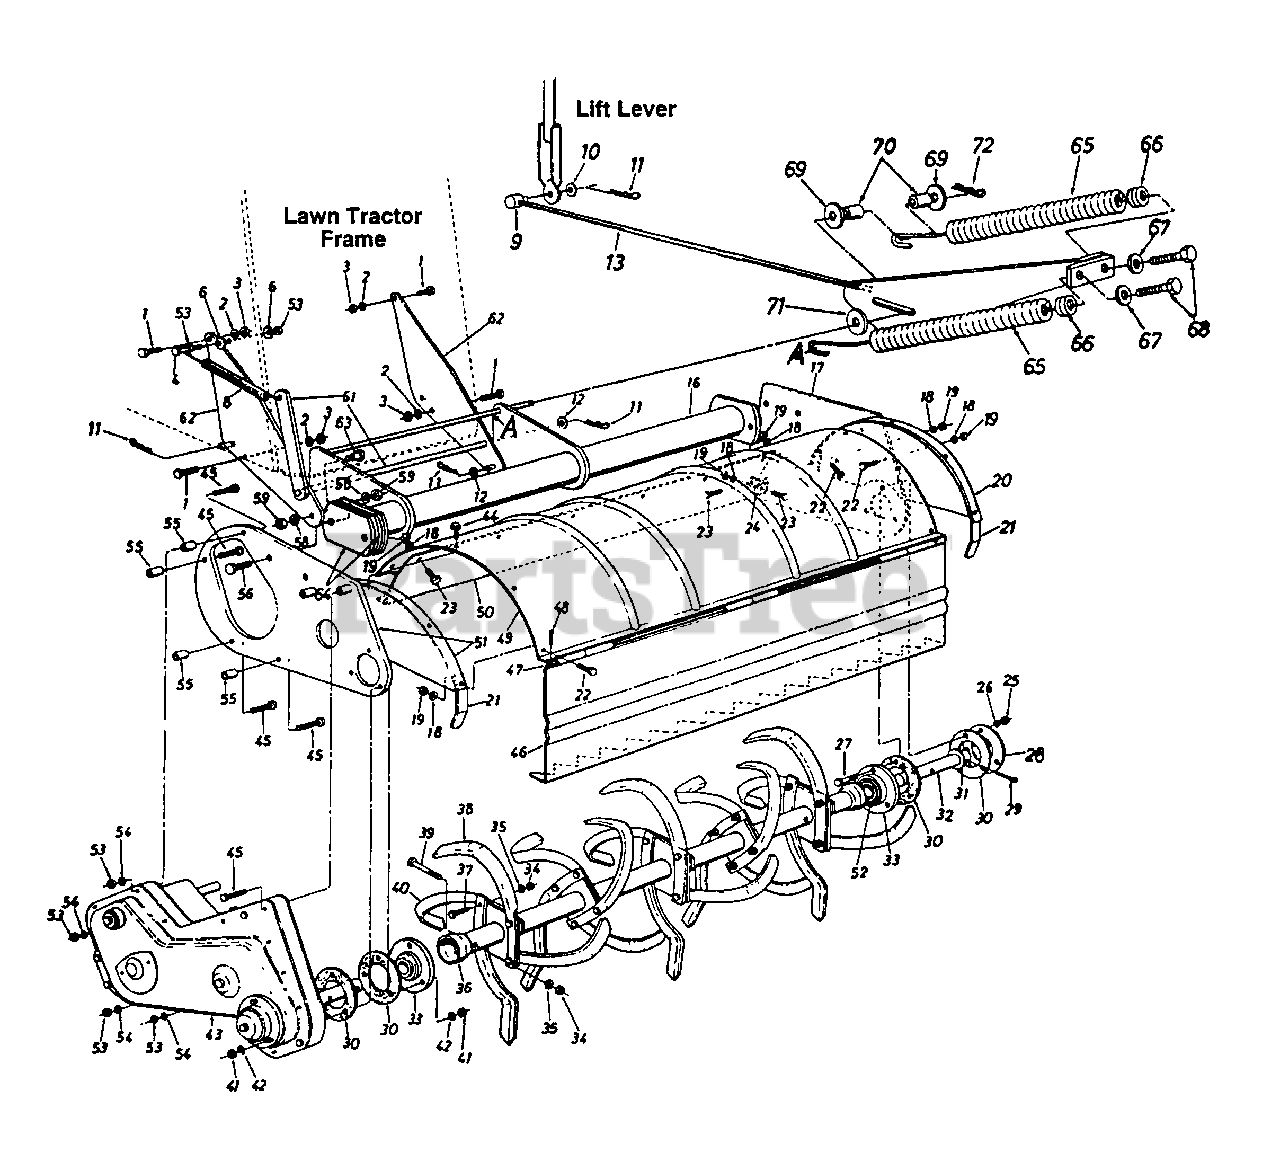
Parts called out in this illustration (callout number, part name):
1	Hex Bolt 3/8-24 x .88" Lg.
2	L-Wash. 3/8" I.D. - H.D.
3	Hex Nut 3/8-24 Thd.
4	Hex Bolt 1/4-20 x 1.25" Lg.
6	Bell-Wash. 1/4" I.D.
8	Ext. Spring 7.75" Lg.
9	Adjustment Ferrule 1/2-13 Thd.
10	Fl-Wash. .64 I.D. x 1.24" O.D. x .06"
11	Intem. Cotter Pin 1/2" Dia.
12	Fl-Wash. .51" I.D. x 1.0" O.D. x .06"
16	Pivot Bracket Assembly
19	Hex Nut 5/16-24 Thd.
23	Hex Bolt 5/16-24 x .62" Eg.
24	Chute Pivot Bracket
25	Hex L-Nut 5/16-18 Thd.
27	Hex Bolt 5/16-18 x 1" Lg. (Grade 5)
30	Gasket for Brg. Housing
31	Fl-Wash. 1.25" I.D. x 2.0" O.D. x .06"
32	Tine Shaft 1.25" Dia. x 6.25" Lg.
33	Bearing Housing w/Bearing
43	Chain Case Ass'y. Comp.
44	Hex TT-Tap Scr. 5/16-18 x .62" Lg.
45	Hex Bolt 1/4-20 x 2.75" Lg.
48	Cotter Pin 1/8" Dia. x 1" Lg.
53	Hex Nut 1/4-20 Thd.
54	L-Wash. 1/4" I.D.
55	Spacer .28" 1.D. x .62" O.D. x .9" Lg.
56	Hex Bolt 1/2-20 x 1.5" Lg.
58	L-Wash. 1/2" I.D.
59	Hex Nut 1/2-20 Thd.
61	Idler Brkt. Support Arm Ass'y.
64	Support Plate
65	Helper Spring
66	Spring Insert
67	Fl-Wash. .34" I.D. x .68" O.D.
68	Hex Bolt 5/16-18 x 3.25" Lg.
69	Fl-Wash. .51" I.D. x 1.5" O.D.
70	Split Spacer. .505" I.D. x .57" Lg.
71	Fl-Wash. .531" I.D. x 1.25" O.D.
72	Internal Cotter Pin 1/2" Dia.
